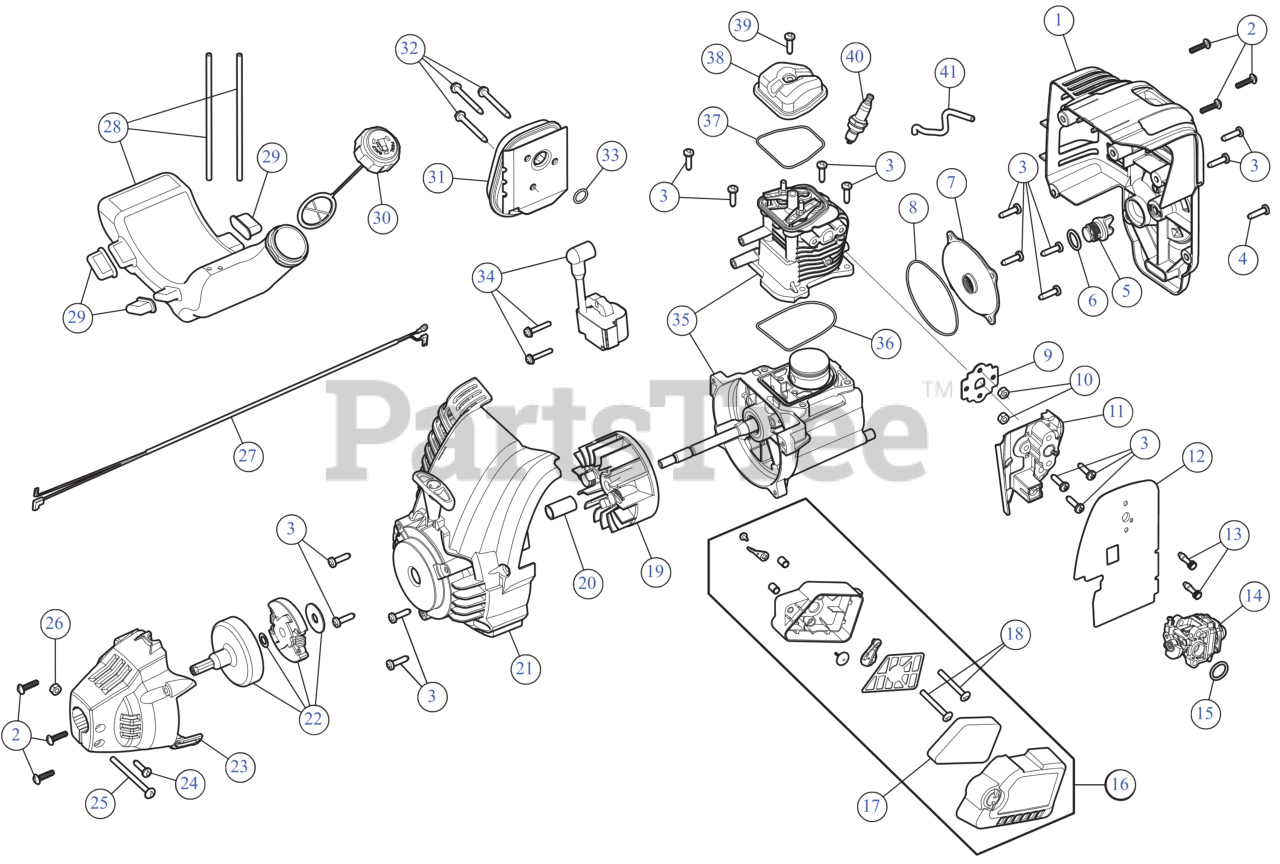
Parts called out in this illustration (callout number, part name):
1	ENGINE COVER ASSEMBLY RR
2	SCREW 8-16 x 3/4
3	SCREW M5-0.8 x 19
4	SCR, M5 x 15.8MM
5	OIL PLUG
6	RING, OIL PLUG (AC
7	CRANKCASE COVER
8	O-RING CRNKCSE CVR
9	GASKET/INSULATOR
10	NUT 10-32
11	INSULATOR
12	CARBURETOR GASKET
13	MOUNTING SCREW
14	CARBURETOR AC3.1
16	AIR CLEANER ASSEMBLY
17	AIR FILTER
18	SCREW 10-32X2.5
19	FLYWHEEL ASSEMBLY AC3.1
20	SPACER :2.165"
21	STARTER HOUSING
22	CLUTCH ASSEMBLY
23	CLUTCH COVER ASSEMBLY
24	SCREW 8-18X.375 T-20
25	SCREW
26	HEX NUT
27	WIRE LEAD
28	FUEL TANK ASSEMBLY
29	FUEL CAP ASSEMBLY 43MM-6 W/O HOLE
30	FUEL TANK PADS
31	MUFFLER ASSEMBLY
32	SCREW M5 x 44MM
33	GASKET/MUFFLER
34	MODULE
35	SHORT BLOCK
36	O-RING CYL AC5
37	O-RING
38	ROCKER COVER
39	SCR, VALVE COVER
40	SPARK PLUG 4 CYCL
41	HOSE, BREATHER
